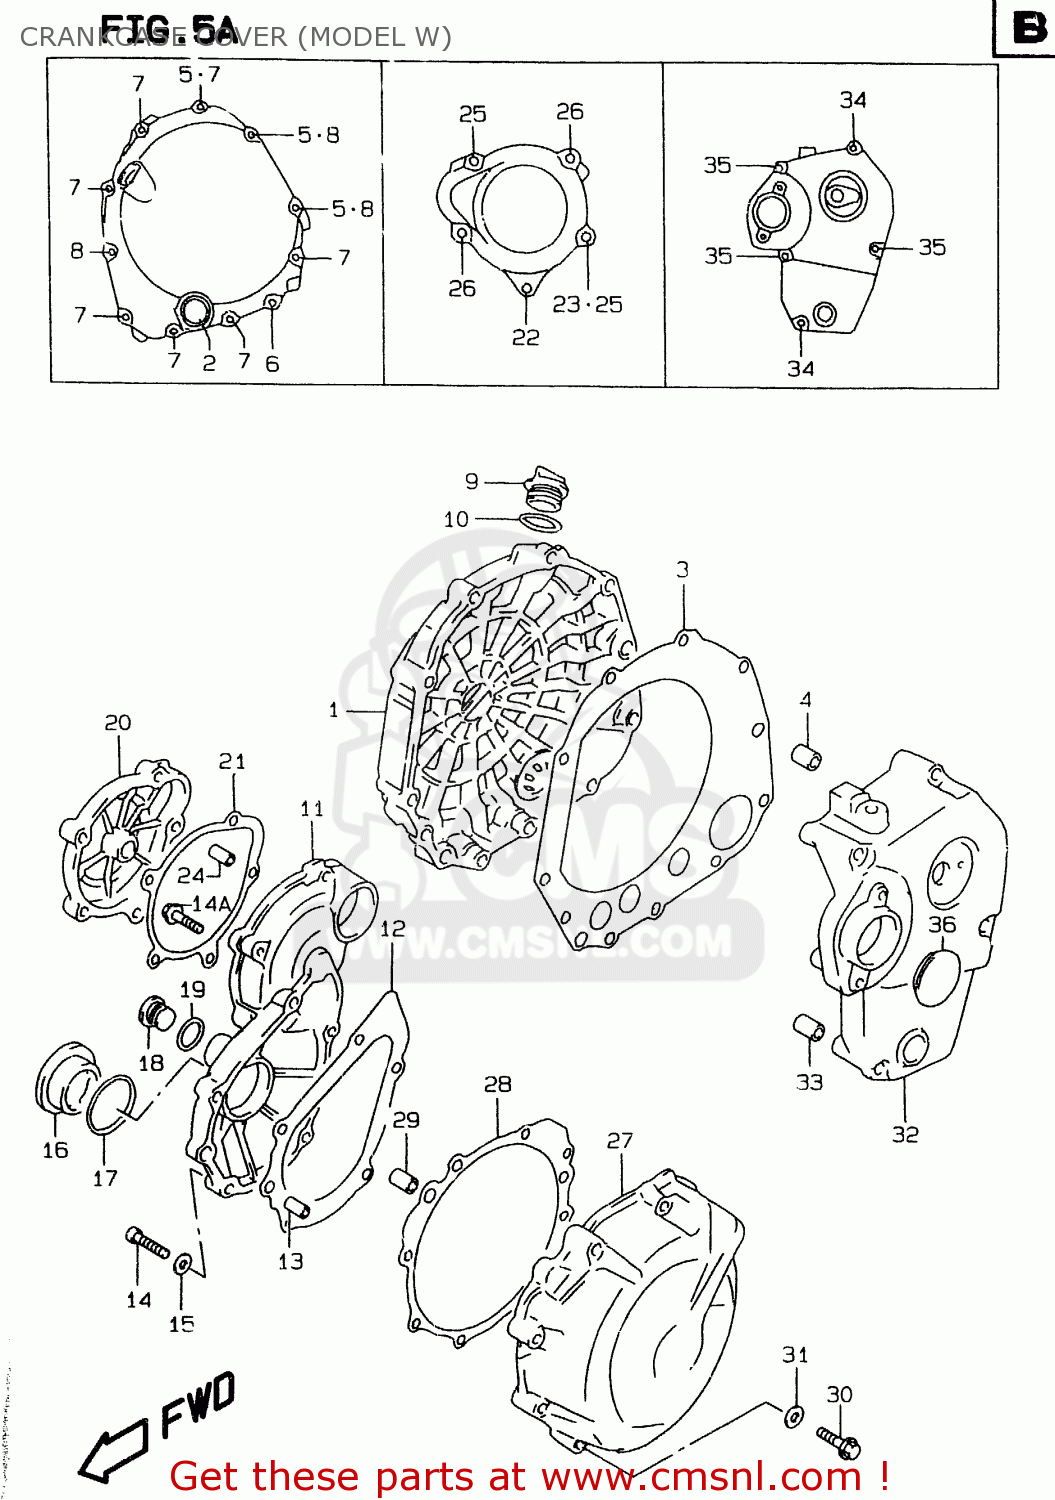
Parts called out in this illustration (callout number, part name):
1	COVER,CLUTCH
2	LENS,OIL LEVEL CHECK
3	GASKET,CLUTCH COVER (NAS)
4	PIN
5	GASKET(5.8X11X1.2) (NAS)
6	BOLT,OIL PAN
7	BOLT
8	BOLT
9	PLUG
10	O RING(D:3.1,ID:16.8)
11	COVER,STARTER CLUTCH
12	GASKET,STARTER CLUTCH COVER
13	PIN
14	BOLT,OIL PAN
14A	BOLT
15	GASKET(5.8X11X1.2) (NAS)
16	PLUG(SILVER)
17	O RING(D:3.1,ID:32.7)
18	PLUG
19	GASKET(16X22X2) (NAS)
20	CAP,STARTER IDLE GEAR
21	GASKET,START IDLE GEAR CAP (NAS)
22	BOLT
23	GASKET(5.8X11X1.2) (NAS)
24	PIN
25	BOLT,OIL PAN
26	BOLT
27	COVER,MAGNETO
28	GASKET,MAGNETO COVER (NAS)
29	PIN
30	BOLT
31	GASKET(5.8X11X1.2) (NAS)
32	COVER,ENGINE SPROCKET
33	PIN
34	BOLT
35	BOLT
36	CAP(OD:36)
